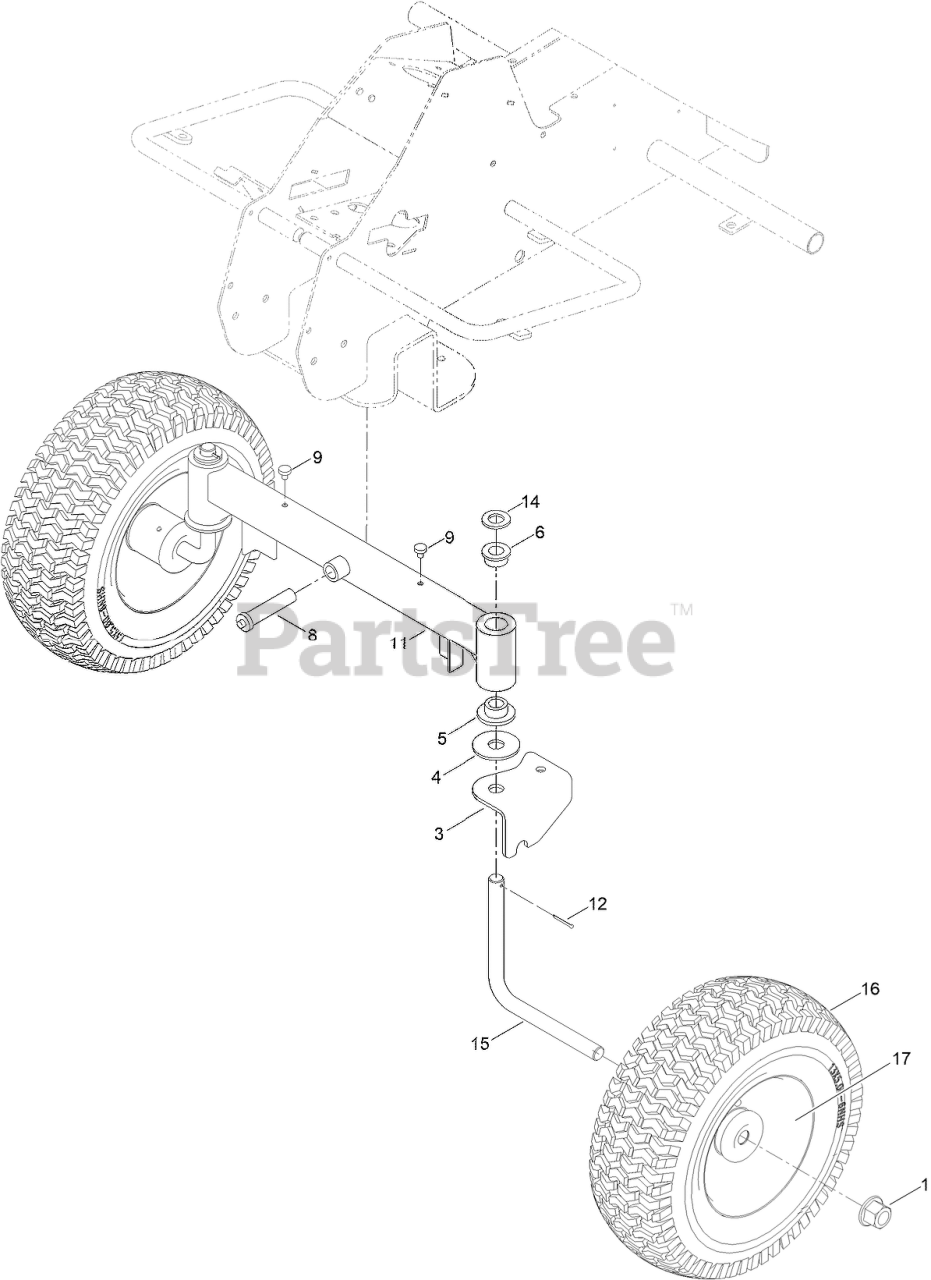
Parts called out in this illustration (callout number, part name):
1	NUT-FLANGE, NI
3	MOUNT FRONT WHEEL
4	WASHER
5	LARGE BUSH, AXLE
6	SMALL BUSH, AXLE
8	PIN, FRONT AXLE TILT
9	STOPPER, FRONT AXLE TILT
11	FRONT AXLE ASM
14	WASHER
15	MOUNT FRONT WHEEL
16	TYRE, WHEEL
17	HUB, WHEEL (FRONT)
